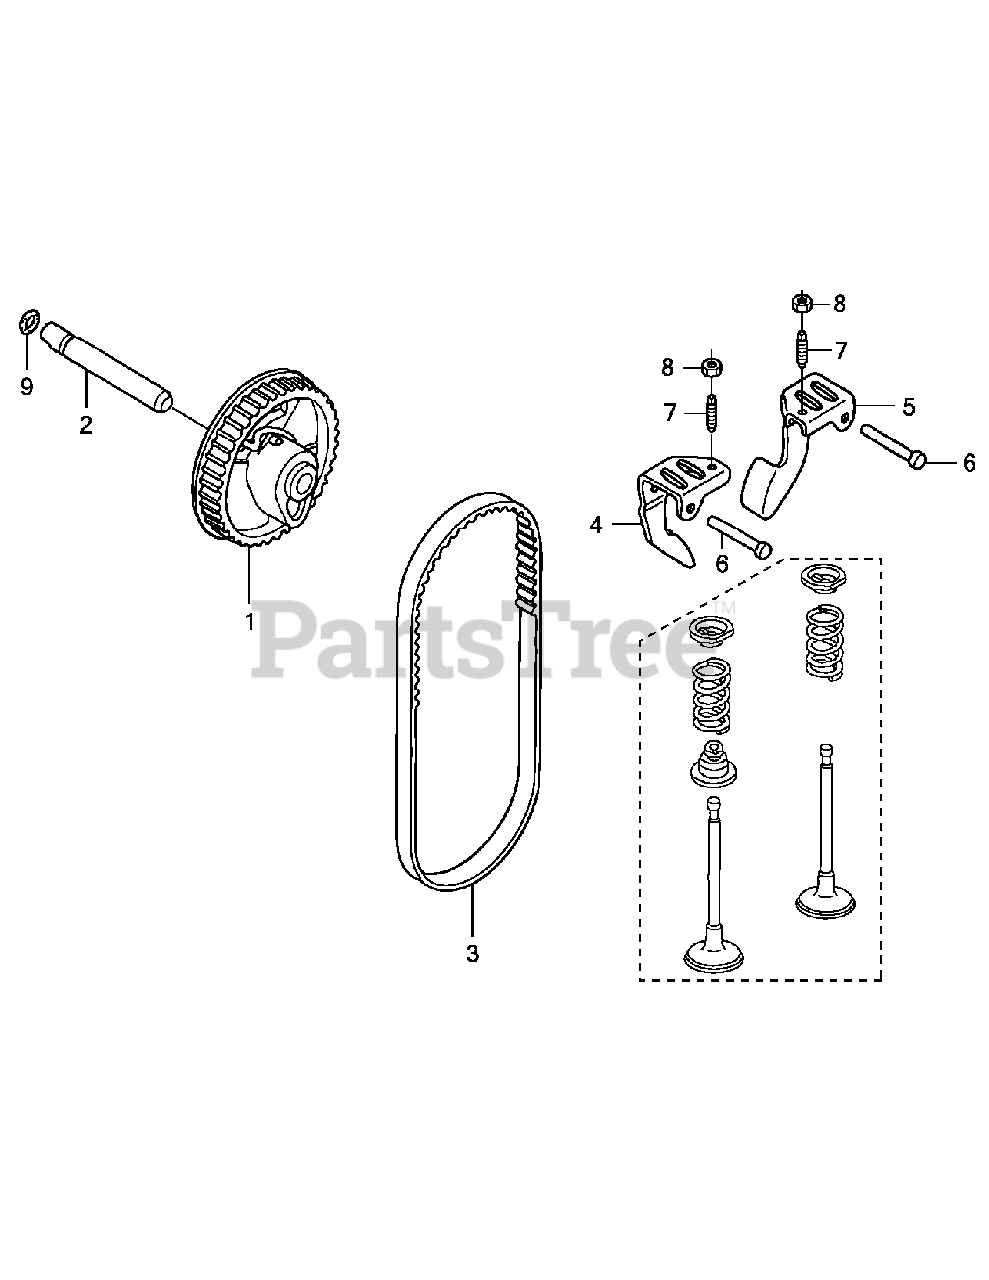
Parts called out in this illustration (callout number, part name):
1	Pulley Complete, Camshaft
2	Shaft, Cam Pulley
3	Belt, Timing (84HU7 G-200)
4	Arm, Inlet Valve Rocker
5	Arm, Exhaust Valve Rocker
6	Shaft, Rocker Arm
7	Screw, Tappet Adjusting
8	Nut, Tappet Adjusting
9	O-Ring 6.8 x 1.9
